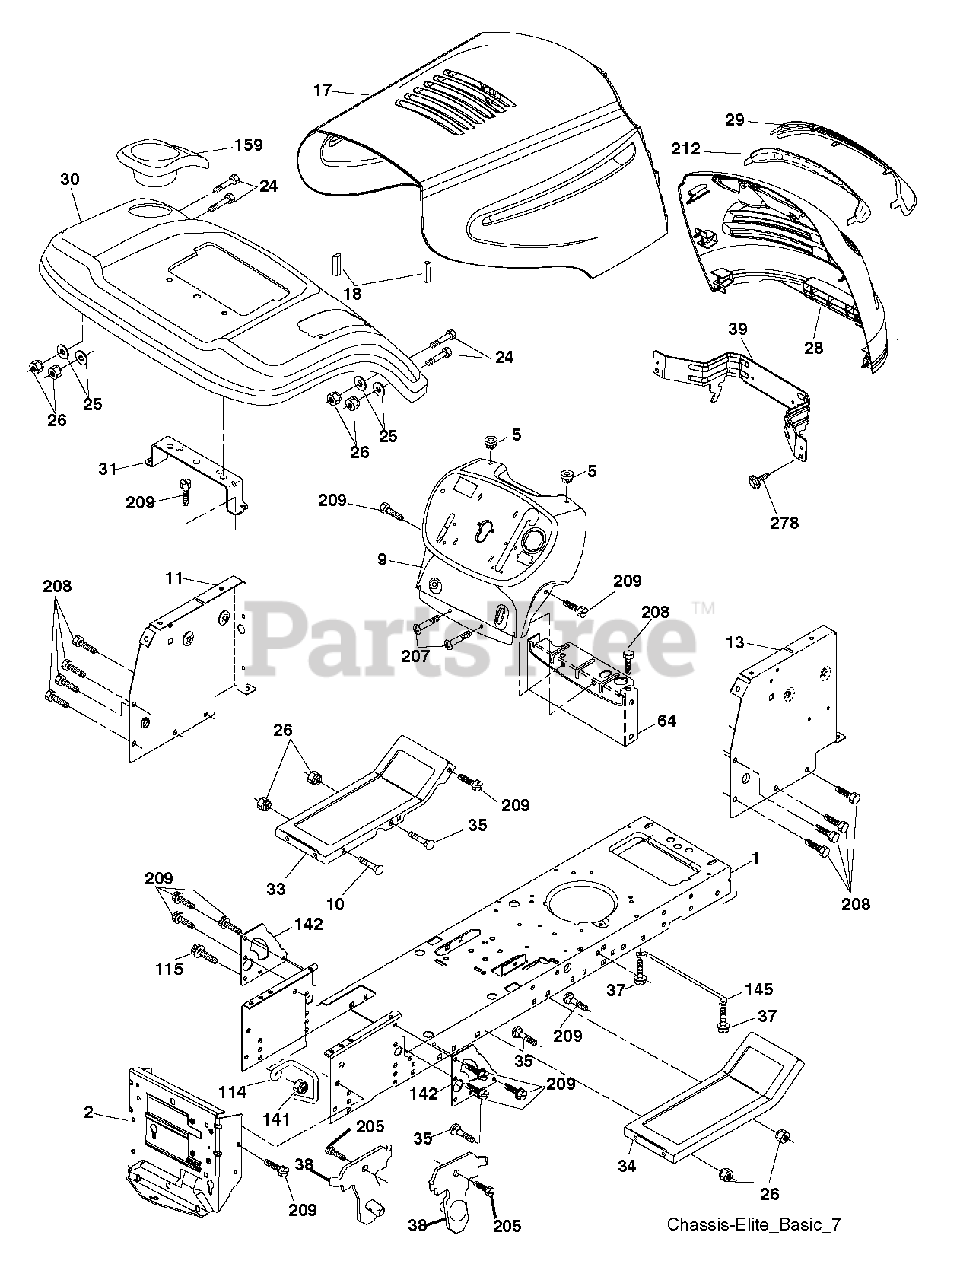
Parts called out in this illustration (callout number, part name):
1	CHASSIS STAMPING
2	DRAWBAR, 12GA
5	BUMPER.RUBBER.HOOD
11	PANEL.DASH.LH.LTX
17	HOOD.STEEL.ELITE.YELLOW
18	BUMPER.HOOD.LARGE.1.75"
25	WASHER
26	NUT
28	GRILLE.ELITE.BASIC.LT.BLACK
29	LENS.GRILLE.BASIC.BAR.LT.CLR
30	FENDER.LTST.W/SHFT.CUP.YELLOW
31	BRACKET FENDER
33	FOOTREST.LH.YELLOW
34	FOOTREST.RH.YELLOW
37	SCREW LT
38	BRACKET.ASM.PIVOT.MOWER.REAR
39	BRACKET PIVOT
64	DASH LOWER
115	SCREW.3/8-16
141	NUT LOCK FLG 3/8-16 UNC
142	PLATE REINFORCEMENT
145	ROD.PIVOT.HOOD
159	CUPHOLDER.BLACK
205	SCREW LT
207	SCREW, 5/16-18 X 1/2
208	SCREW 3/8-16X1/2
209	SCREW, 3/8-16X3/4
212	INSERT.LENS.REFLECTIVE.LEFT
278	SCREW.#10 X 0.750.BOS (2 2)
